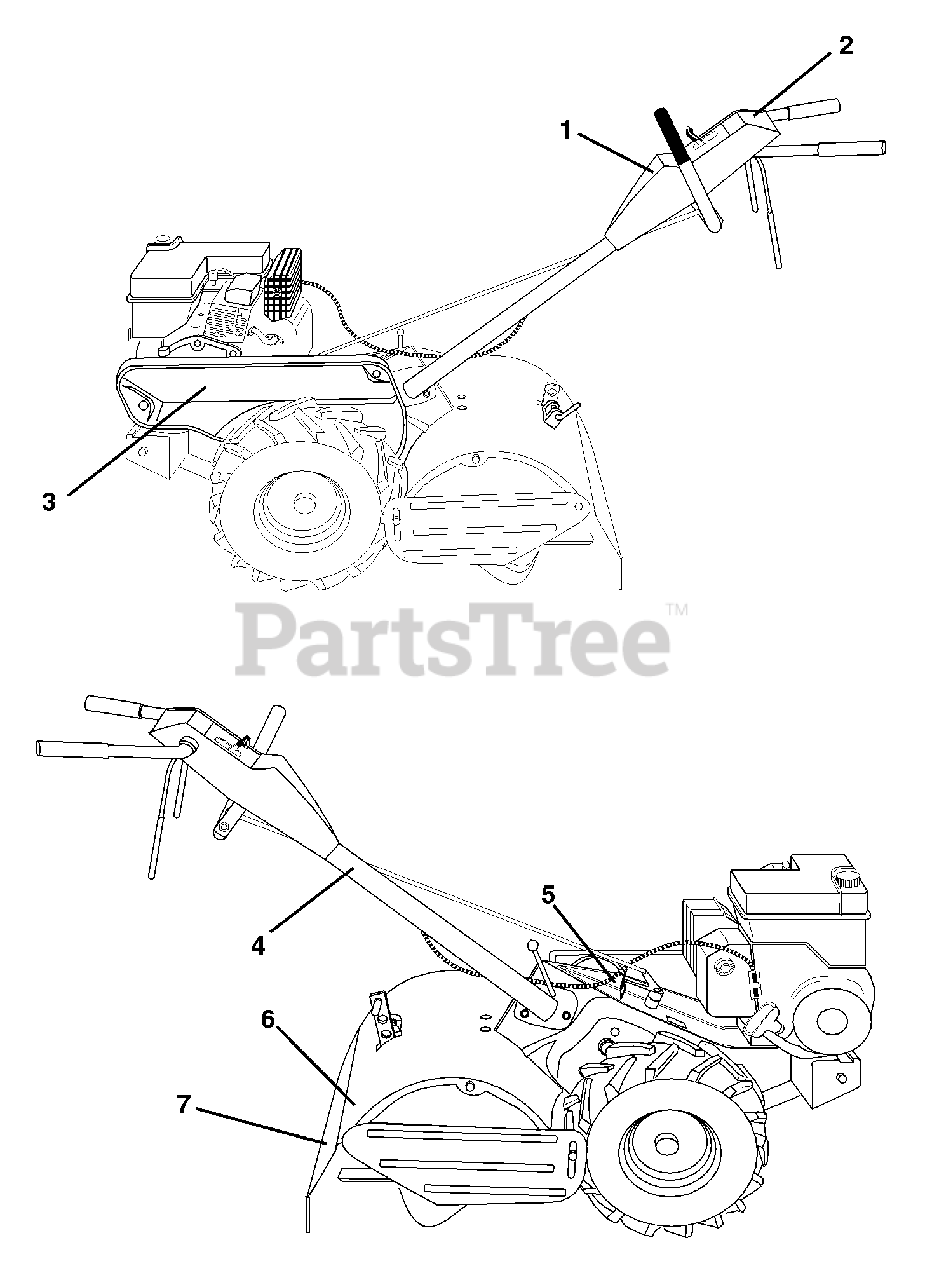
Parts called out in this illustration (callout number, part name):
1	Decal, Logo
2	Decal, Logo
3	Decal, Logo
4	Decal, Hand Placement
5	Decal, Shift Indicator
6	Decal, Caution
7	Decal, Warning, Rotating Tines
